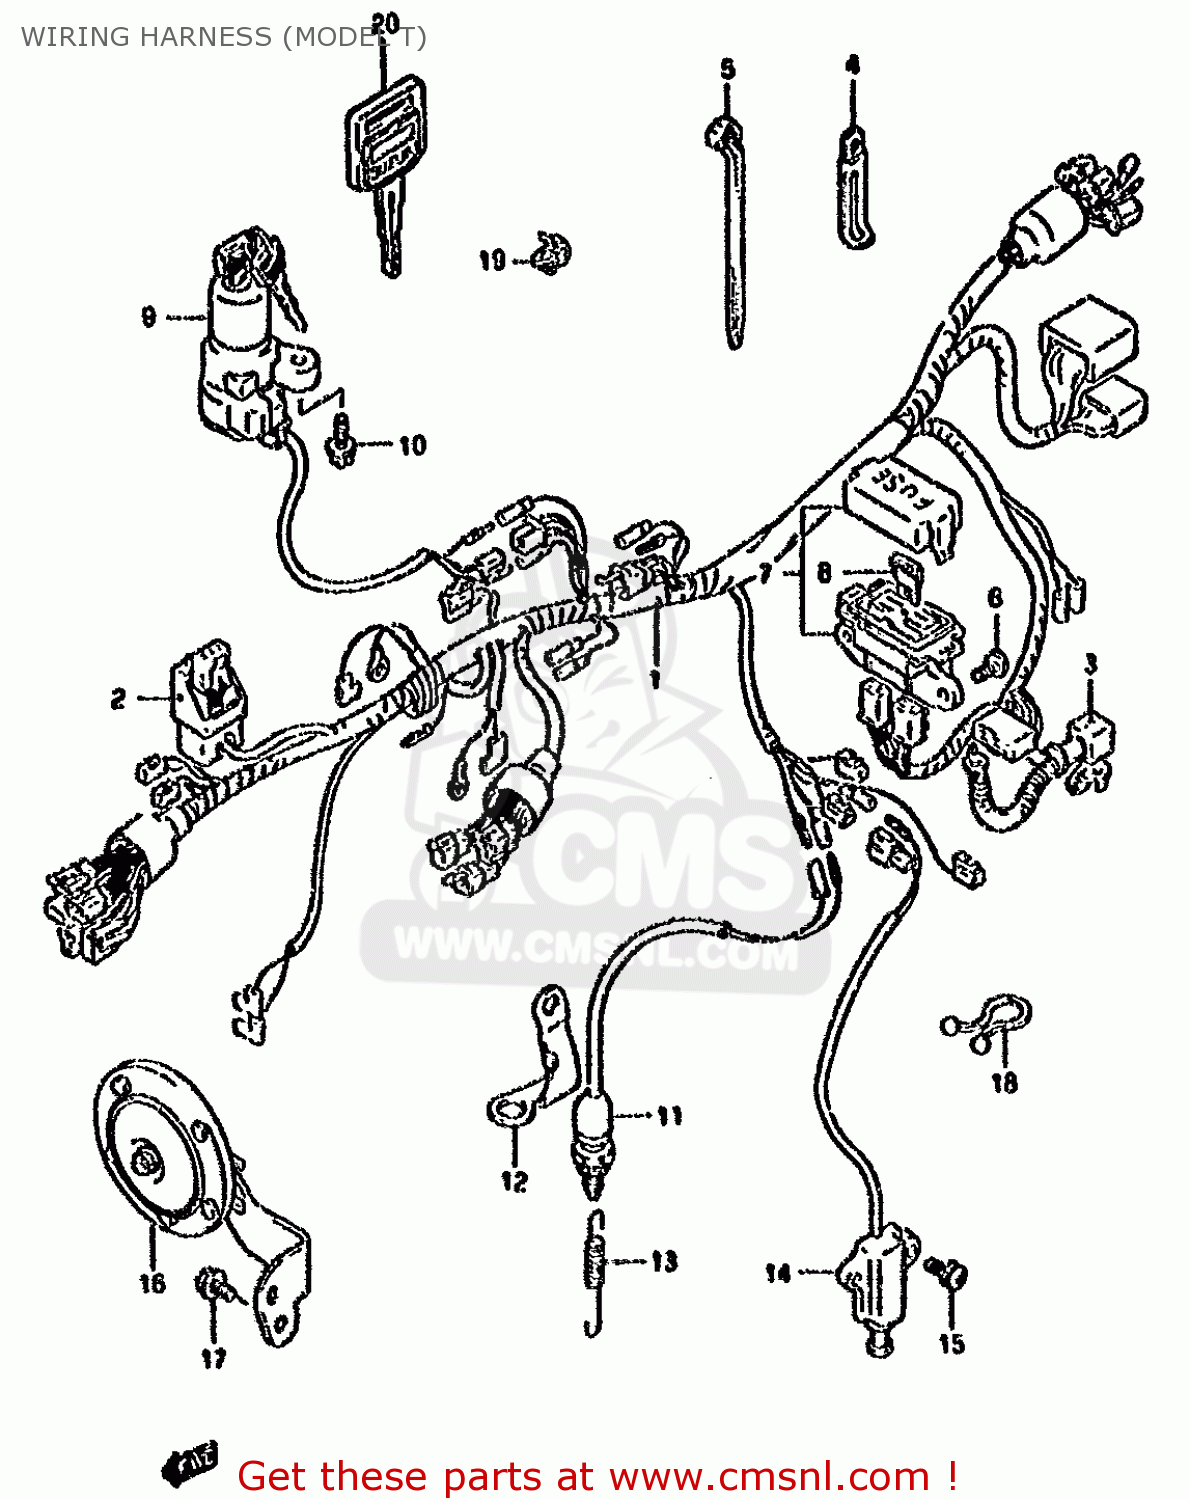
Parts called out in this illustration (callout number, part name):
1	HARNESS, WIRING
2	COVER,DECOMPRESSION CONTROL UNIT
3	CAP,BATTERY PLUS
4	CLAMP(L:65)
5	CLAMP(L:95)
6	SCREW 6X12
7	BOX ASSY,FUSE
8	FUSE(10A)
9	LOCK ASSY,STEERING
10	SCREW(6X18)
11	SWITCH ASSY,STOP LAMP
12	BRACKET,STOP LAMP SWITCH
13	SPRING
14	SWITCH ASSEMBLY,SIDE STAND
15	SCREW
16	HORN ASSY
17	BOLT
18	CLIP(ID:11.5)
19	CLAMP
20	KEY,BLANK
